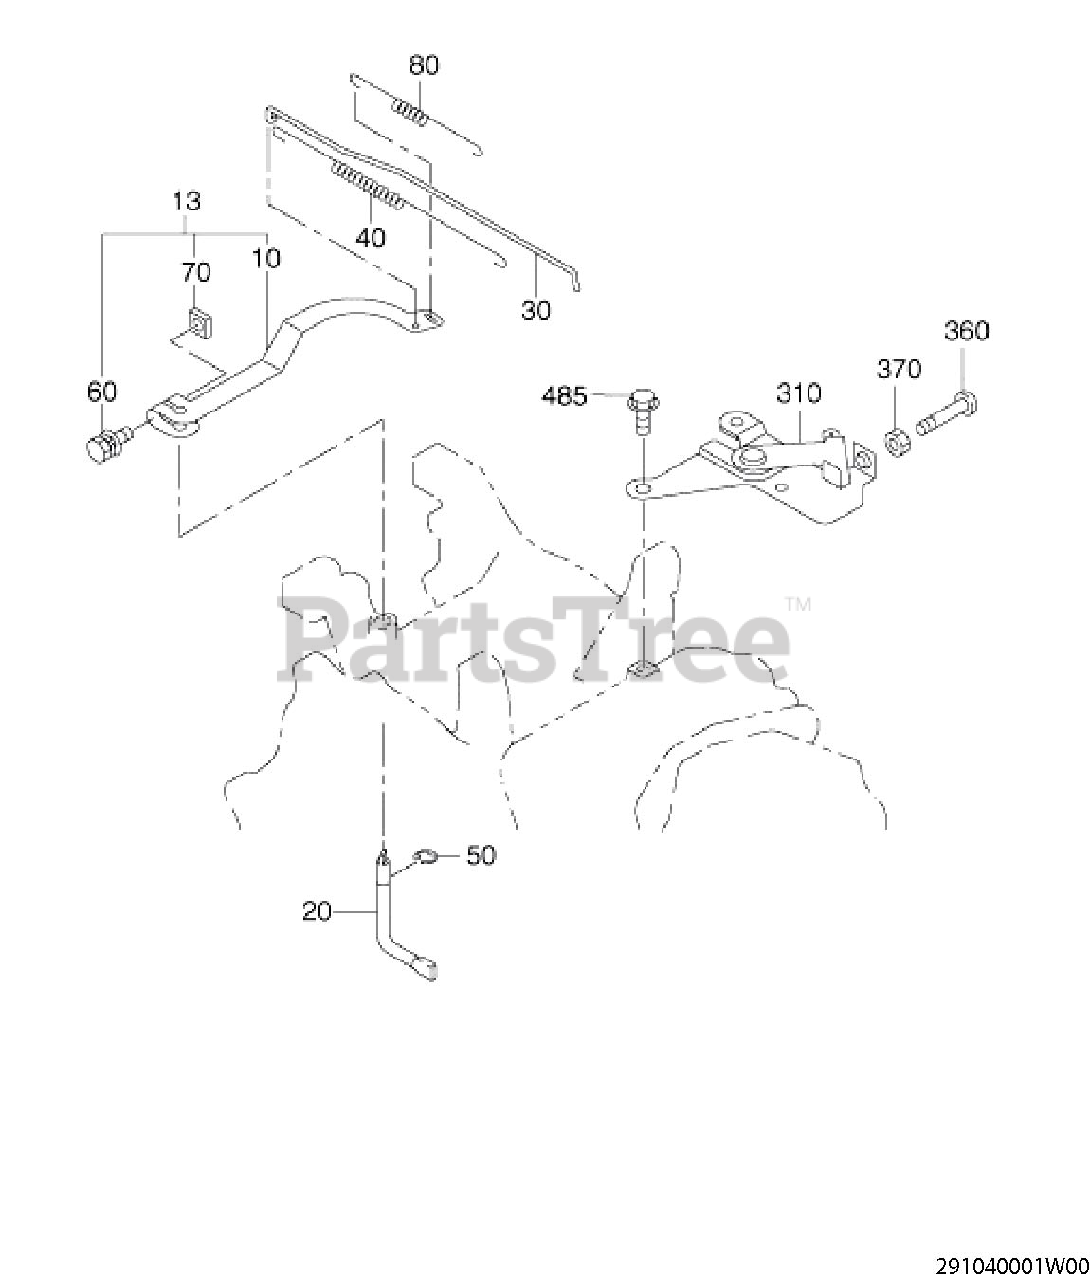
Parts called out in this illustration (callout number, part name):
13	GOVERNOR LEVER AY
20	GOVERNOR SHAFT
40	ROD SPRING
50	CLIP
60	BOLT AND WASHER AY
70	NUT
80	GOVERNOR SPRING
310	SPEED CONTROL CP
360	SCREW
370	NUT
485	FLANGE BOLT
